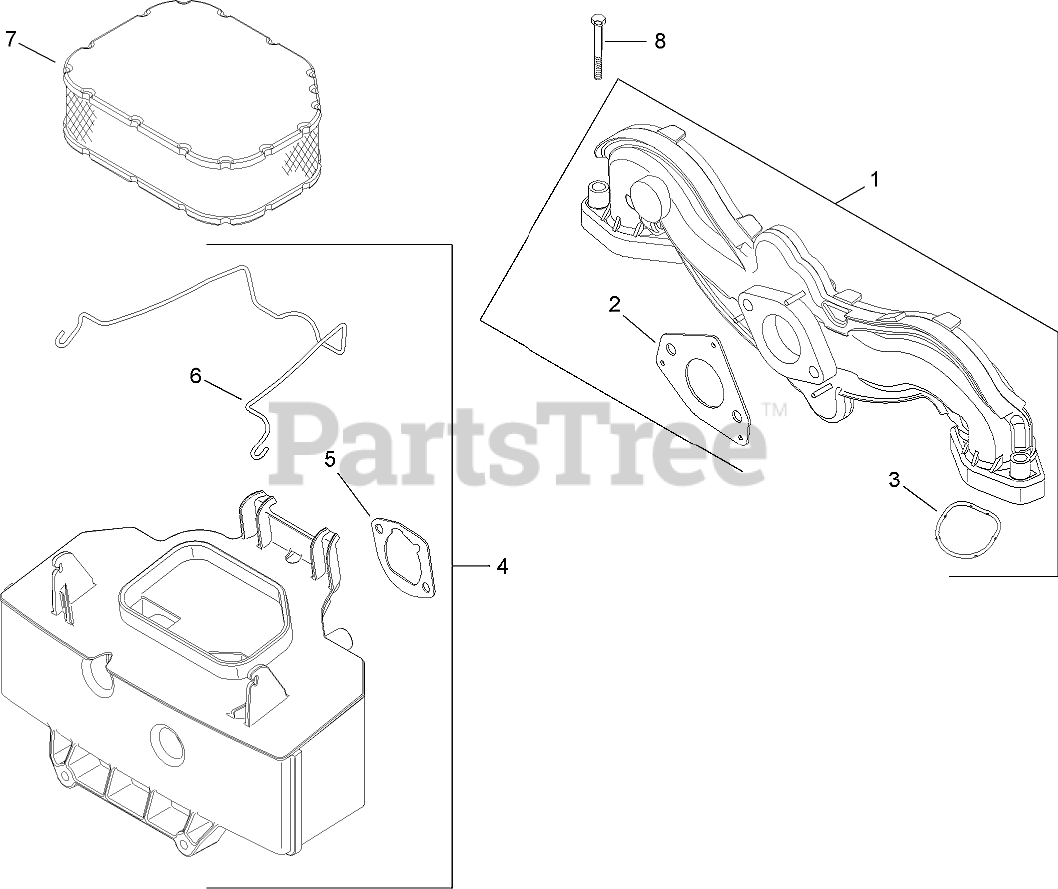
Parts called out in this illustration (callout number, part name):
1	Manifold-Intake (Includes 2-3)
2	GASKET-CARBURETOR
3	O-RING
4	Base-Air Cleaner (Includes 5-6)
5	GASKET-BASE, AIR CLEANER
6	LATCH-ELEMENT, AIR CLEANER
7	Element-Air Cleaner
8	SCREW-FLANGE (M6X1.0X40)
